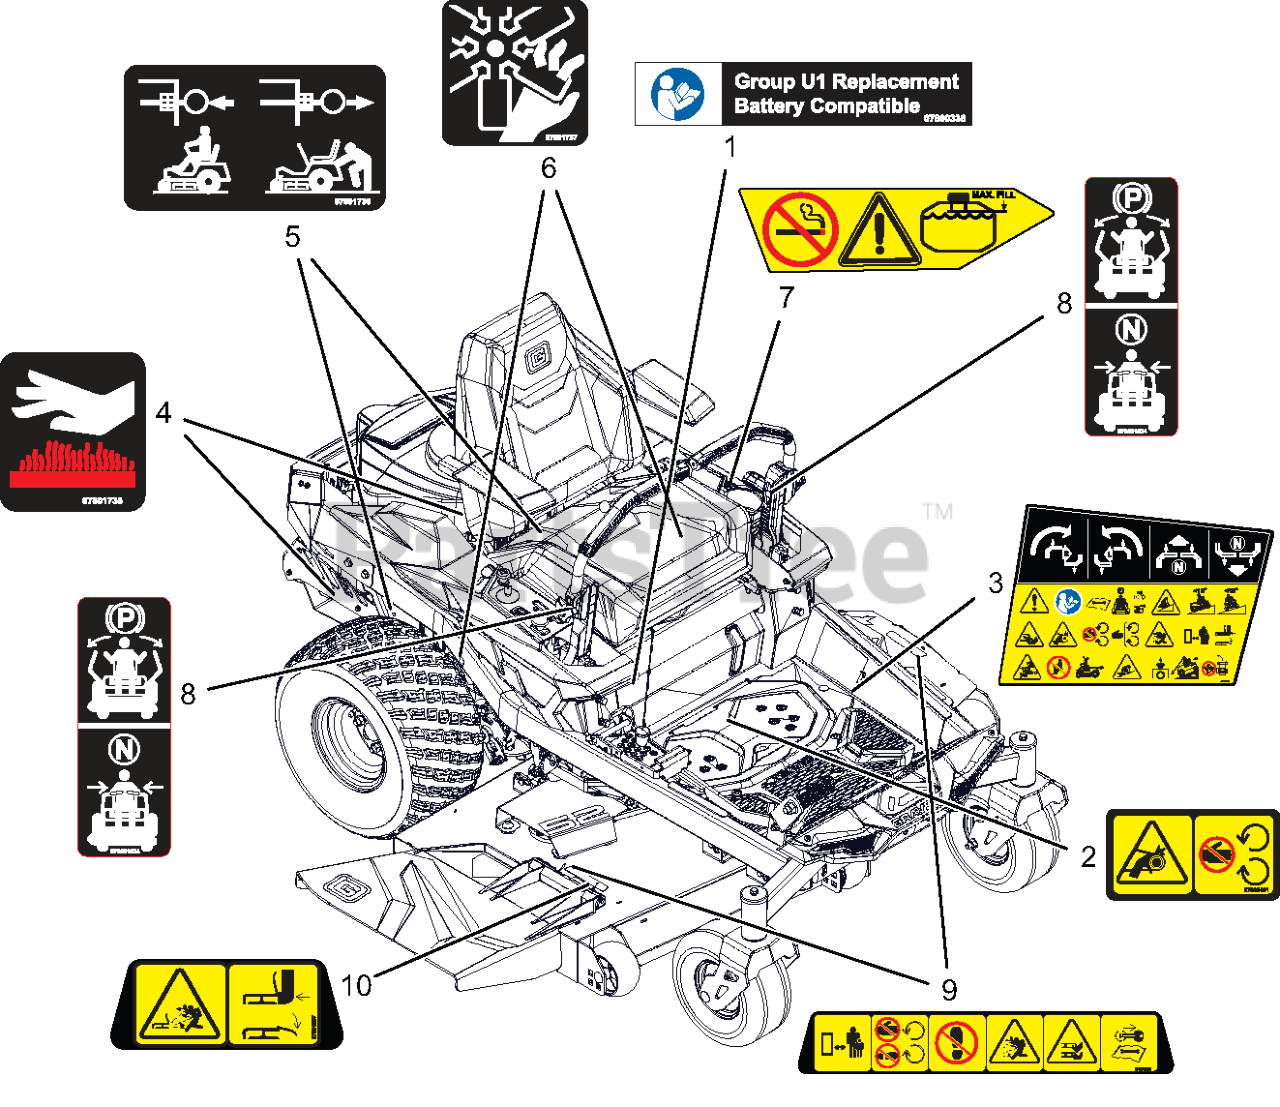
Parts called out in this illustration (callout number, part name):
1	DECAL, U1 BATTERY REPLACEMENT
2	DECAL, SAFETY - GUARDING
3	DECAL- MAIN SAFETY-INSTRUCTION
4	DECAL,SAFETY HOT SURFACE
5	DECAL,TRANSAXLE DISCONNECT
6	DECAL, DANGER FAN
7	DECAL, FUEL WARNING
8	DECAL- STEERING-BRAKE
9	DECAL- SAFETY - MOWER DECK
10	DECAL- SAFETY - DECK GUARDING
